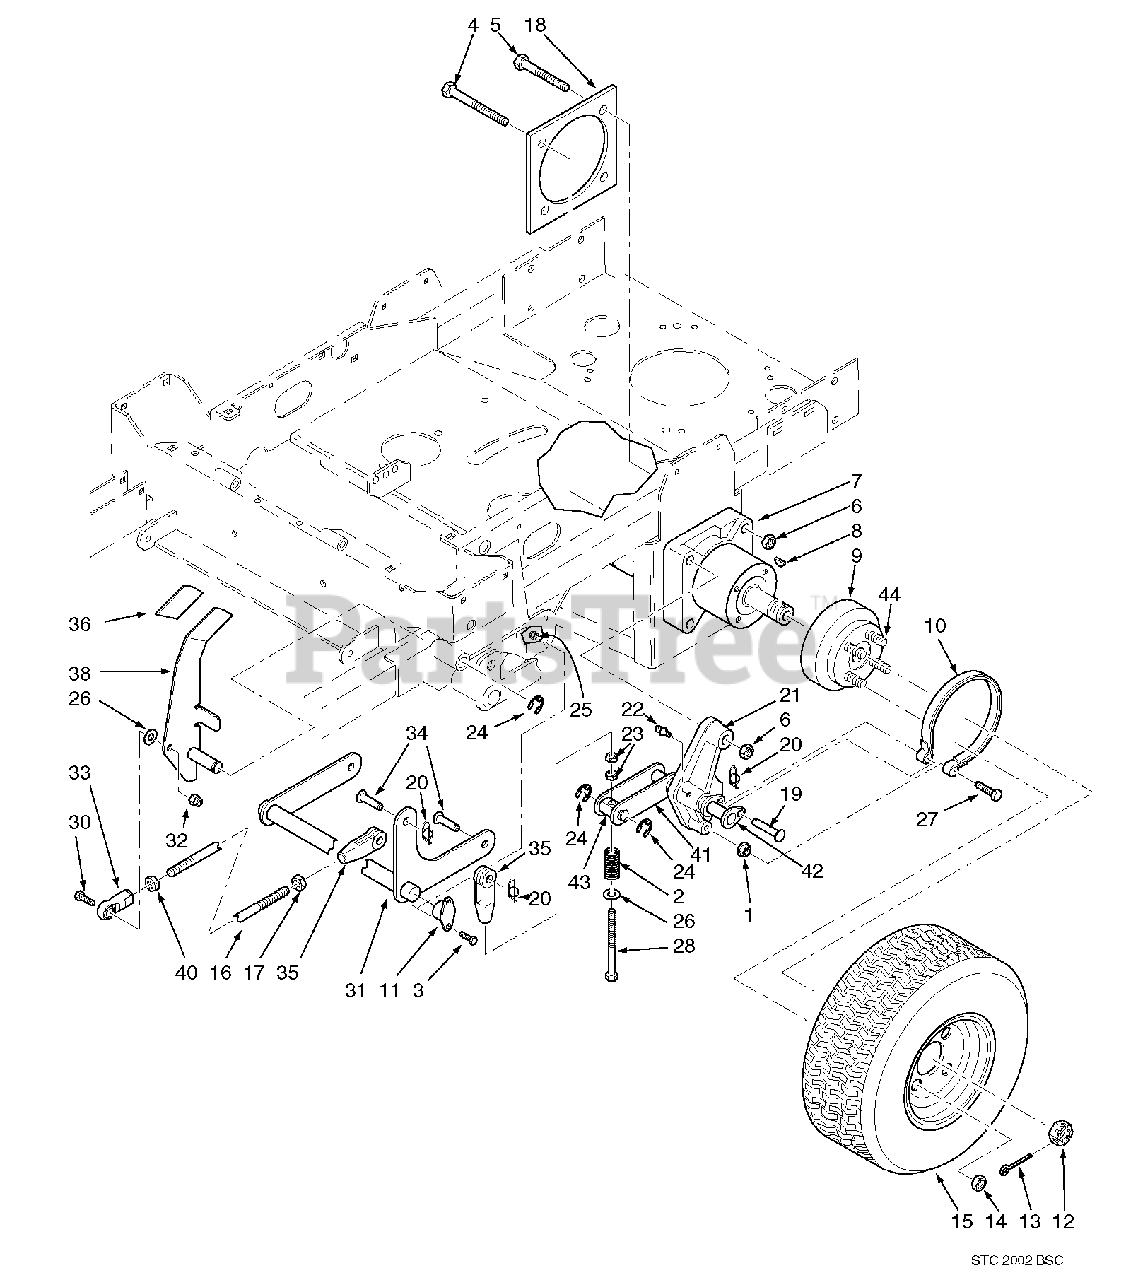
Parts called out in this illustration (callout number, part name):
1	Nut, Serr. Flng. 1/2-13
2	Spring
3	Bolt, Hex Hd. 5/16-18 x 3/4"
4	Bolt, Hex Hd. 1/2-13 x 4"
5	Bolt, Hex Hd. 1/2-13 x 2-1/2"
6	Nut, 1/2-13 Center Lock
7	Wheel Motor, Parker
8	Key, Woodruff 5/16 x 1"
9	Wheel Hub Assembly
10	Brake Band Assembly
11	Bushing, Self Align
12	Nut, Hex Castle 1.0-20 UNEF
13	Cotter Pin, 9/64 x 1-1/2"
14	Lug Nut, 1/2-20
15	Wheel Assembly 24 x 9.5-12
15	Wheel Assembly 24 x 12-12
15	Rim
15	(48"/52") Tire 24 x 9.5 - 12
15	Tire 24 x 12 - 12
16	Brake Rod Stud, 3/8-24 x 8-1/8"
17	Nut, 3/8-24 UNF
18	Plate Weldment, Motor Backing
19	Clevis Pin, 3/8 x 1.93"
20	Pin, Rue Cotter 3/8" Dia.
21	Brake Linkage LH
22	Grease Fitting, 1/4-28
23	Nut, 3/8-24 UNF
24	Retaining Ring, .625" Ext.
25	Nut, Elastic Stop 5/16-18
26	Flatwasher, 3/8 (.391 x .938 x .105")
27	Bolt, Hex Hd. 1/2-13 x 2-1/2" Grd. 8
28	Bolt, Hex Hd. 3/8-24 x 3-3/4"
29	Cotter Pin, 3/32 x 3/4"
30	Bolt, Hex Hd. 3/8-16 x 1-1/2"
31	Brake Shaft
32	Nut, Elastic Stop 3/8-16
33	Rod End, 3/8-24 LH Thread
34	Clevis Pin, 3/8 x 1.06"
35	Clevis, 3/8-24
36	Grip, Brake Lever
37	Nut, Serr. Flng. 3/8-16
38	Brake Lever
39	Bolt, Hex Hd. 3/8-16 x 2-3/4"
40	Nut, 3/8-24 UNF-2B LH Thread
41	Lever, Brake
42	Shaft Weldment, Pivot
43	Pin, Pivot
44	Bolt, Serr. Flng. 1/2-20 x 4.563"
